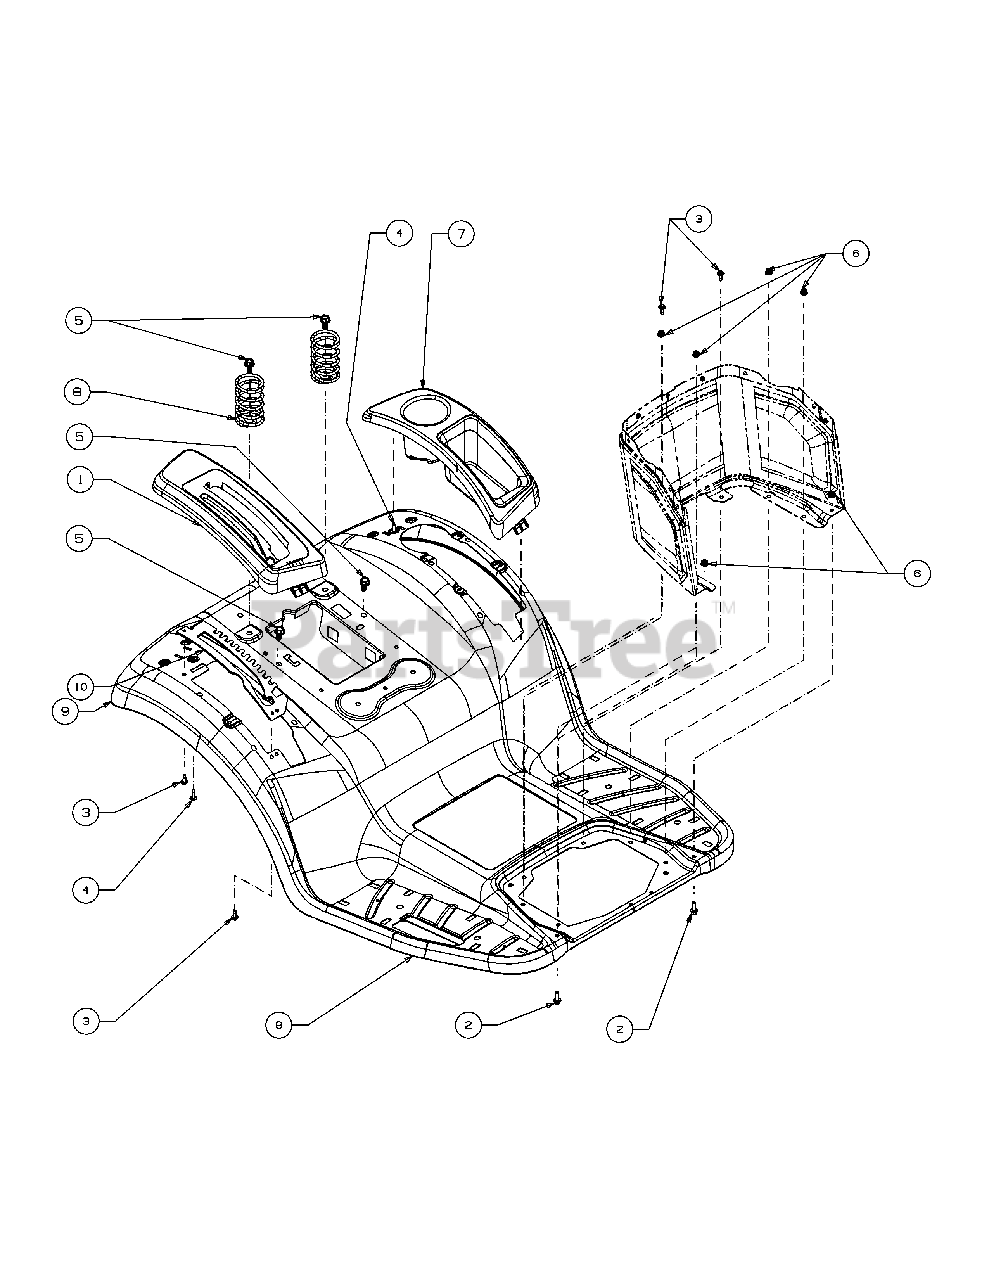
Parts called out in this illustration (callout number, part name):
1	Cover-Fndr Rh Lift/P
2	Screw Hhflg:1/4-20:.75
3	Screw-Hxacrnwsh M6-
4	Screw-Hxacrnwsh 1/4
5	Screw-Hex Wash Sf
7	Cover-Fndr Lh Cup Hldr
8	Spring-Compression Seat
9	Fender-Rear
